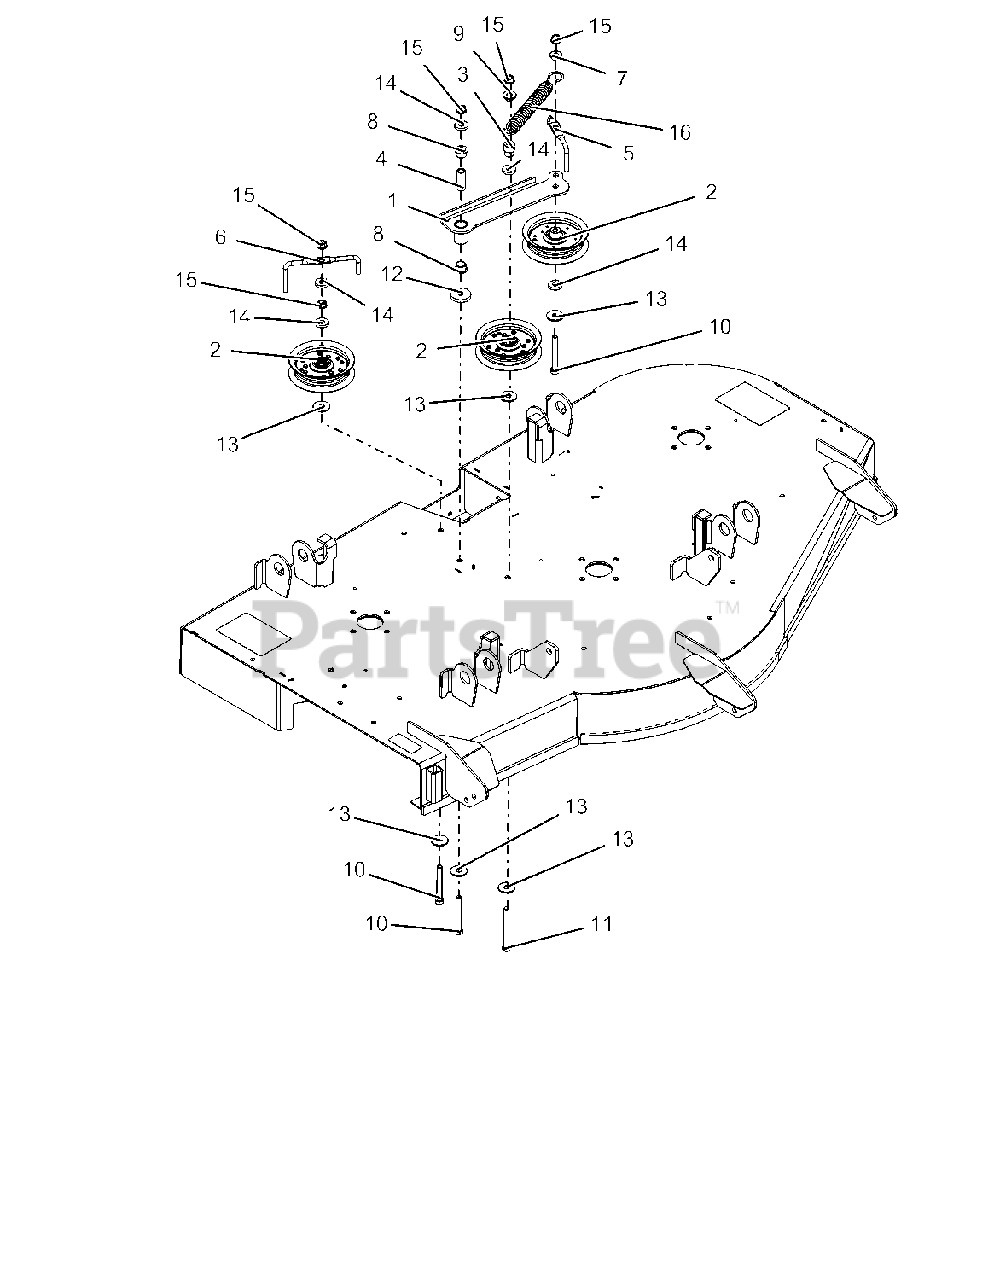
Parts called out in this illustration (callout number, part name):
1	WLDMT, IDLER ARM-52"
2	ASM, IDLER 4"
3	BUSHING, IDLER (P/M)
4	SPACER, .375IDX.625ODX1.66 PM
5	WIREFORM, BELT FINGER
6	WIREFORM, BELT FINGER
7	BSHG-FLG .385X.500X.875X.406
8	BSHG-FLG, .625X.750X.500X1.00
9	BSHG-FLG .385X.500X.875X.31
10	BLT-HEX .38-16X3.00 GR5 FTH YZ
11	@BLT-HEX .38-16X3.50 GR5 YWZC
12	WSHR,FLT STL.406X1.50X.245YWZC
13	@WSHR-FL-STL .406X1.25X.10 ZC
14	WSHR-FL-STL .406X1.00X.188 YWZ
15	@NUT-LK-TOP-FLG .38-16 YWZC
16	SG-TENS .135X.98X6.0 WLD 62
